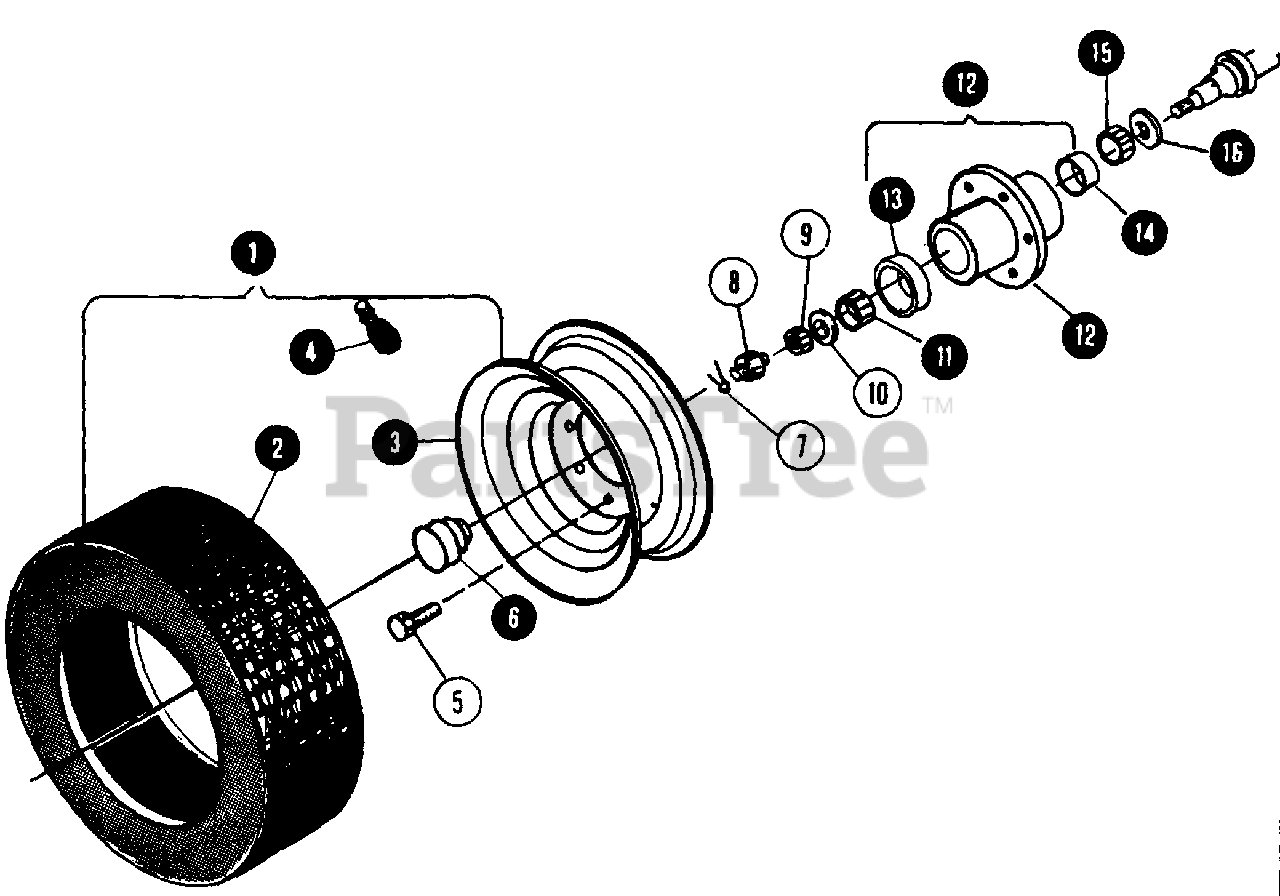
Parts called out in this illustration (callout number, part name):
1	WHEEL ASSEMBLY
2	TIRE, TUBELESS
3	RIM
4	VALVE, AIR
5	BOLT, 3/8NF x 23/32 HEX SPACIAL LUG
6	CAP, WHEEL HUB GREASE
7	COTTER-PIN, 5/32 x 1-1/4
8	RETAINER, HUB TO SPINDLE NUT
9	NUT, 3/4 NF HEX
10	WASHER, 49/64" FLAT
11	BEARING, CONE HUB TO SPINDLE
12	HUB, FRONT WHEEL-ASSEMBLY
13	CUP, OUTER HUB
14	CUP, INNER HUB
15	BEARING, HUB TO SPINDLE - INNER
16	SEAL, HUB TO SPINDLE
